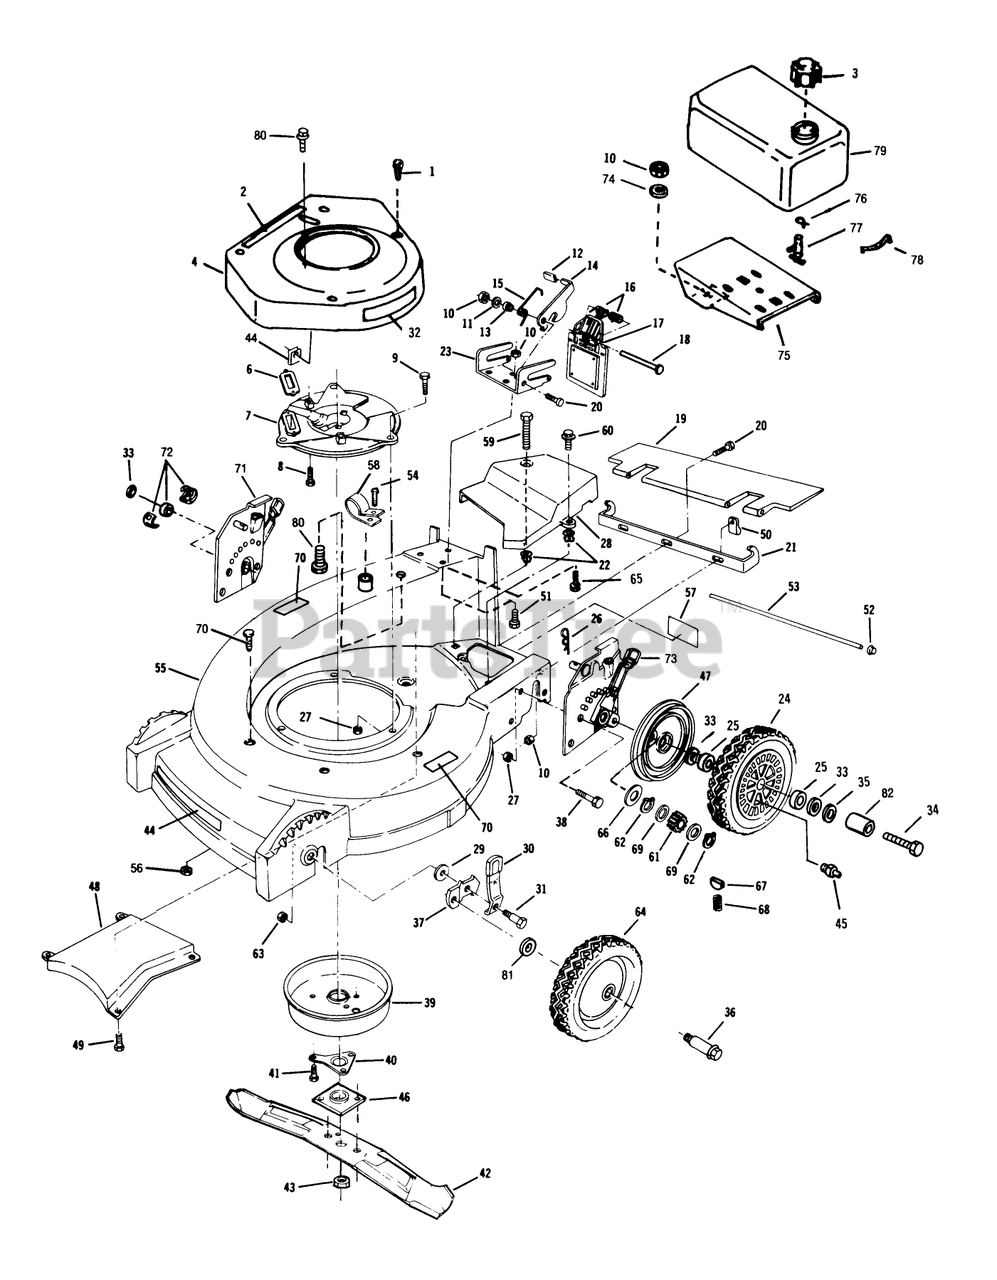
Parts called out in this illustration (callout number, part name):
1	SCREW - SELF TAPPING
3	FUEL CAP & INSERT
7	M/PLATE
8	SCREW V
9	SCREW-HH
10	LOCKNUT E
12	KNOB (S&R)
15	SPRING
16	SPRING ASOC
18	ROD (RB&W)
19	T/SHIELD SM&P
26	HAIR PIN
27	NUT-LOCK F
29	WASHER
30	SPRING ARM ASM
31	BOLT
33	WASHER
35	SPACER
36	BOLT-SHOULDER
39	MUFFLER COVER F
40	SUPPORT F
41	SCREW
43	NUT-BLADE
44	Retainer
45	FITTING LINCOLN
46	PLATE AND COLLAR ASM
48	BAFFLE CHUTE PL
51	SCREW
54	SCREW LAWRENCE
56	NUT-LOCK F
60	SCREW
61	PINION BROCKWAY
62	RET RING
63	LOCKNUT
65	SCREW HEX WASHER
66	THRUST WASHER
67	KEY
68	SPRING
69	SPACER/GR ALGHNY
72	REAR AXLE BEARING
74	WASHER
75	BRACKET - TANK
76	CLAMP - HOSE S
77	VALVE&SCREEN SM
78	SPRING
80	SCREW SEMS SM
81	WASHER WROUGHT
